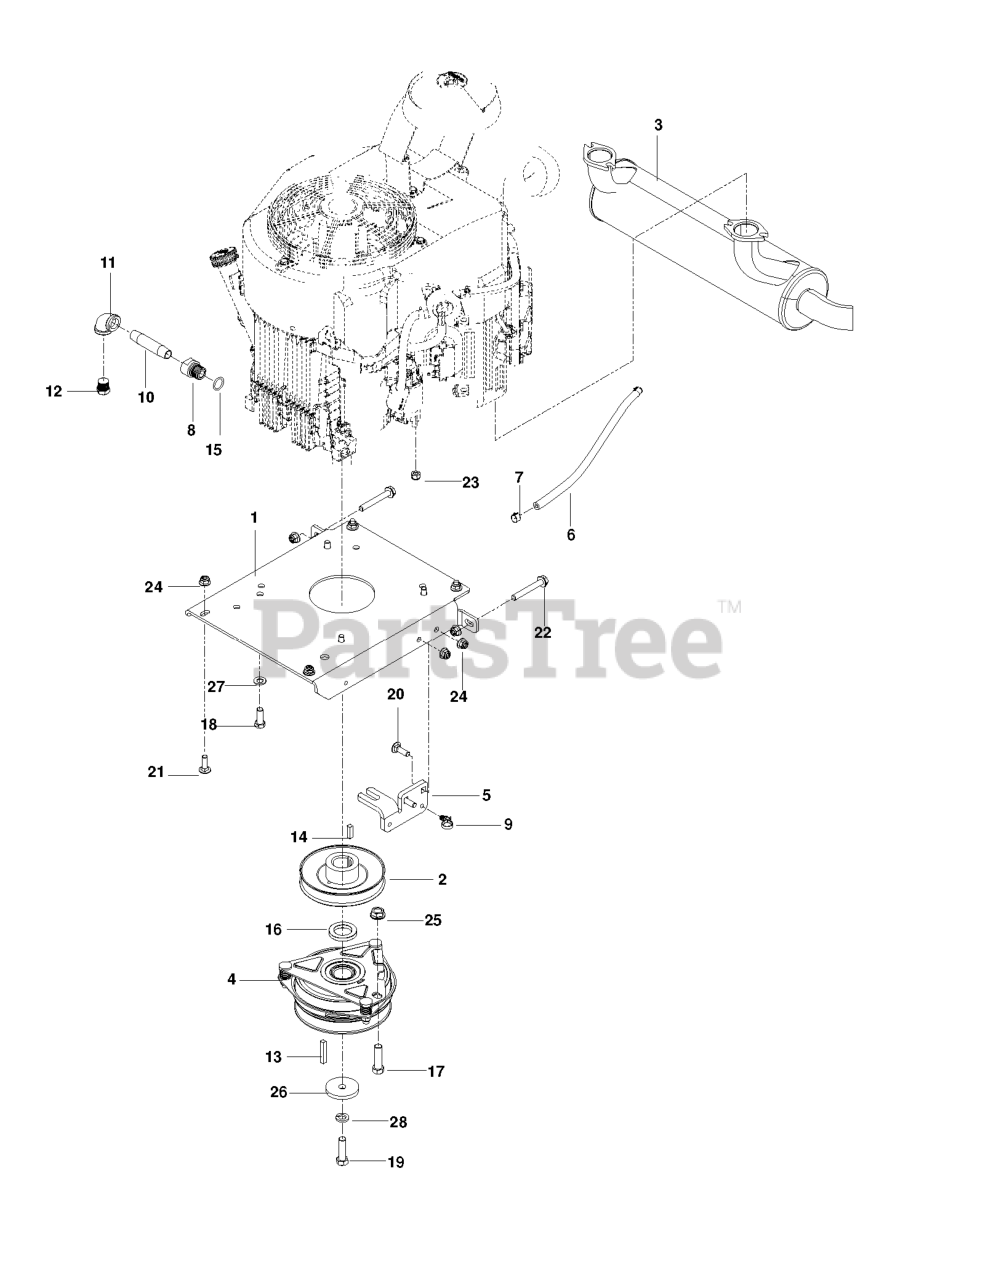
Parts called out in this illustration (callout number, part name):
1	PLATE.ENGINE.BLACK
2	PULLEY, ENGINE
3	MUFFLER, 29HP KAW FX751V-850V
4	CLUTCH, 150 FT/LBS
5	STOP, CLUTCH, OGURA
6	GAS LINE 10"
7	HOSE CLAMP
8	ADAPTER, OIL DRAIN
9	TIE WRAP, 8-3/8", W/CLIP
10	PIPE NIPPLE 3/8 X 3
11	90 DEG.ELBOW 3/8NPT
12	PLUG, DRAIN 3/8 NPTF
13	KEY 1/4 SQ X 2
14	KEY 1/4 SQ X 1.0
16	SPACER, .25 X 1.135 I.D.
17	HCS 7/16-14 X 1-1/4 GR 5 ZD
18	HCS 3/8-16X1.GRD.5.ZD
19	HCS 7/16F X 1 1/2
20	RHSNB 5/16C X 1
21	RHSNB 5/16C X 1
22	HHFS 5/16-18 X 2.25 GD 5
23	JAM NUT 1/4C (2 2 PW01)
24	5/16-18 NYLOC FLANGE NUT
25	NUT 7/16C WHIZ
26	BLADE WASHER
27	WASHER, 3/8 DISC SPRING SPEC
28	WASHER 7/16 LOCK
